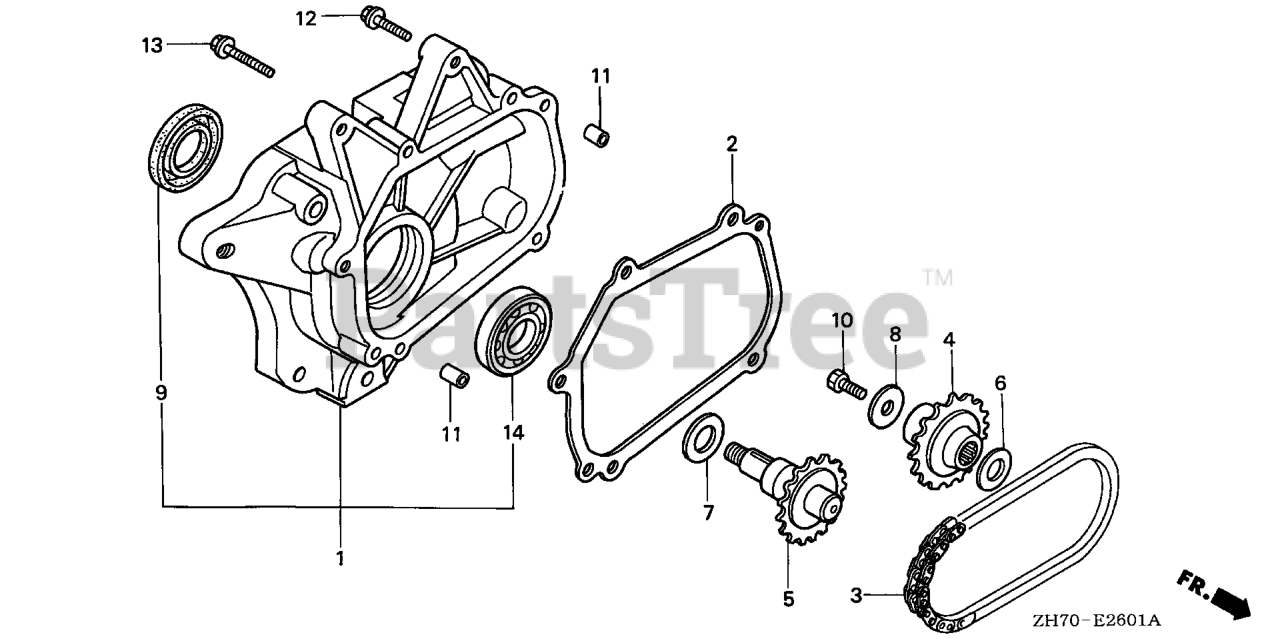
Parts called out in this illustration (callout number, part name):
1	COVER ASSY., CHAIN CASE
2	GASKET, CHAIN CASE COVER
3	CHAIN, P.T.O. DRIVE
4	SPROCKET, DRIVE (17T)
5	SHAFT, P.T.O. (16T)
6	WASHER, THRUST (20X1.00)
7	SPRING, THRUST
8	WASHER (8MM)
9	OIL SEAL (25X38X7)
9	OIL SEAL (25X38X7) (ARAI)
10	BOLT, HEX. (8X25)
11	PIN C, DOWEL (8X14)
12	BOLT, FLANGE (8X35)
13	BOLT, FLANGE (8X55)
14	BEARING, RADIAL BALL (6005)
